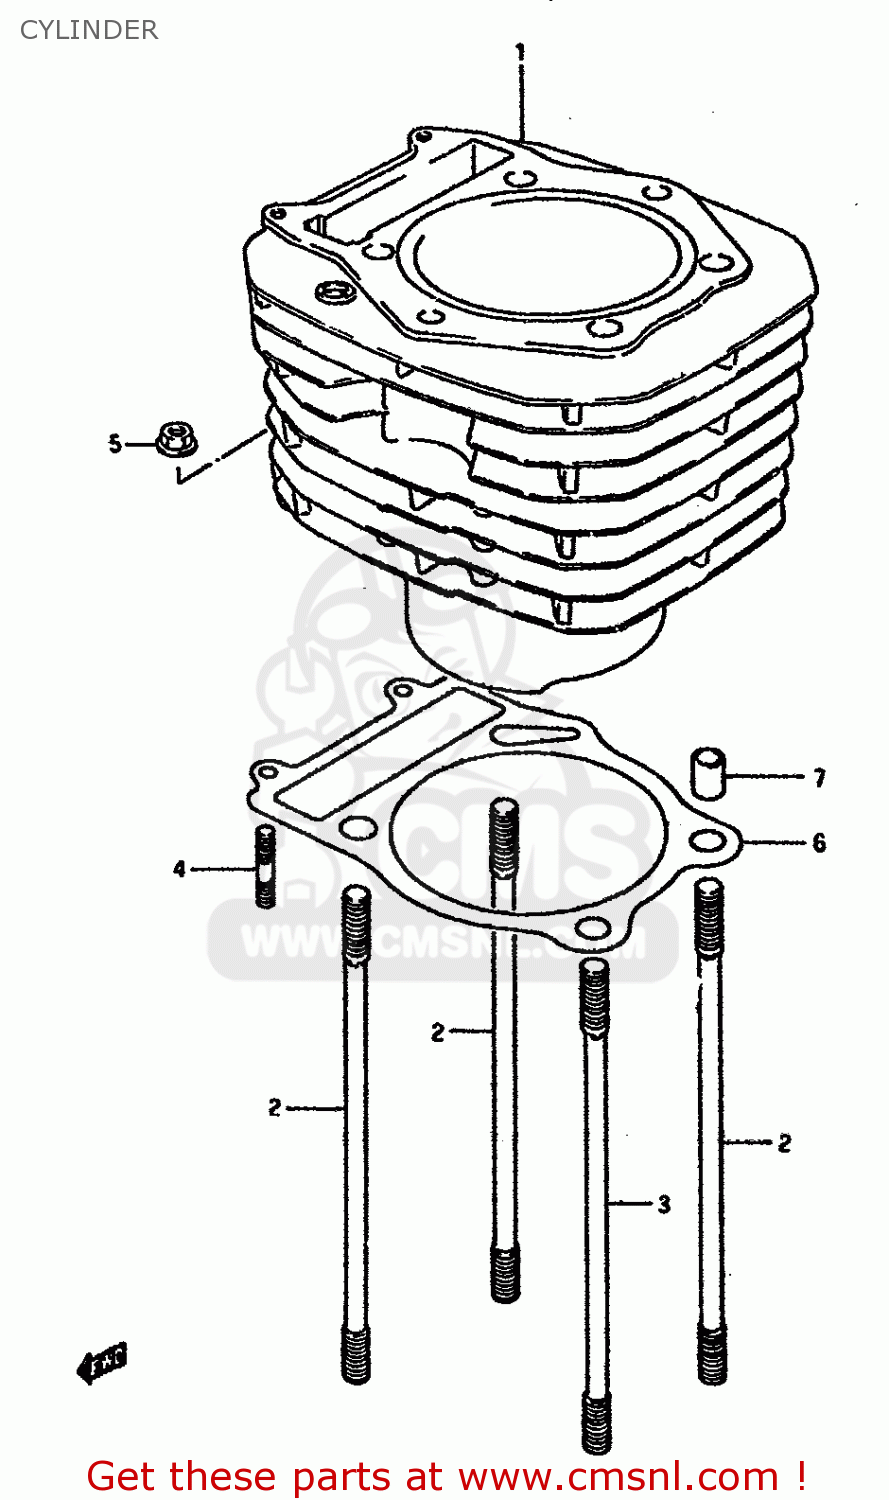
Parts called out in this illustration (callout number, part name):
1	CYLINDER
2	STUD
3	STUD
4	STUD BOLT L:20
5	NUT 6MM
6	GASKET,CYLINDER (MCA)
7	PIN
